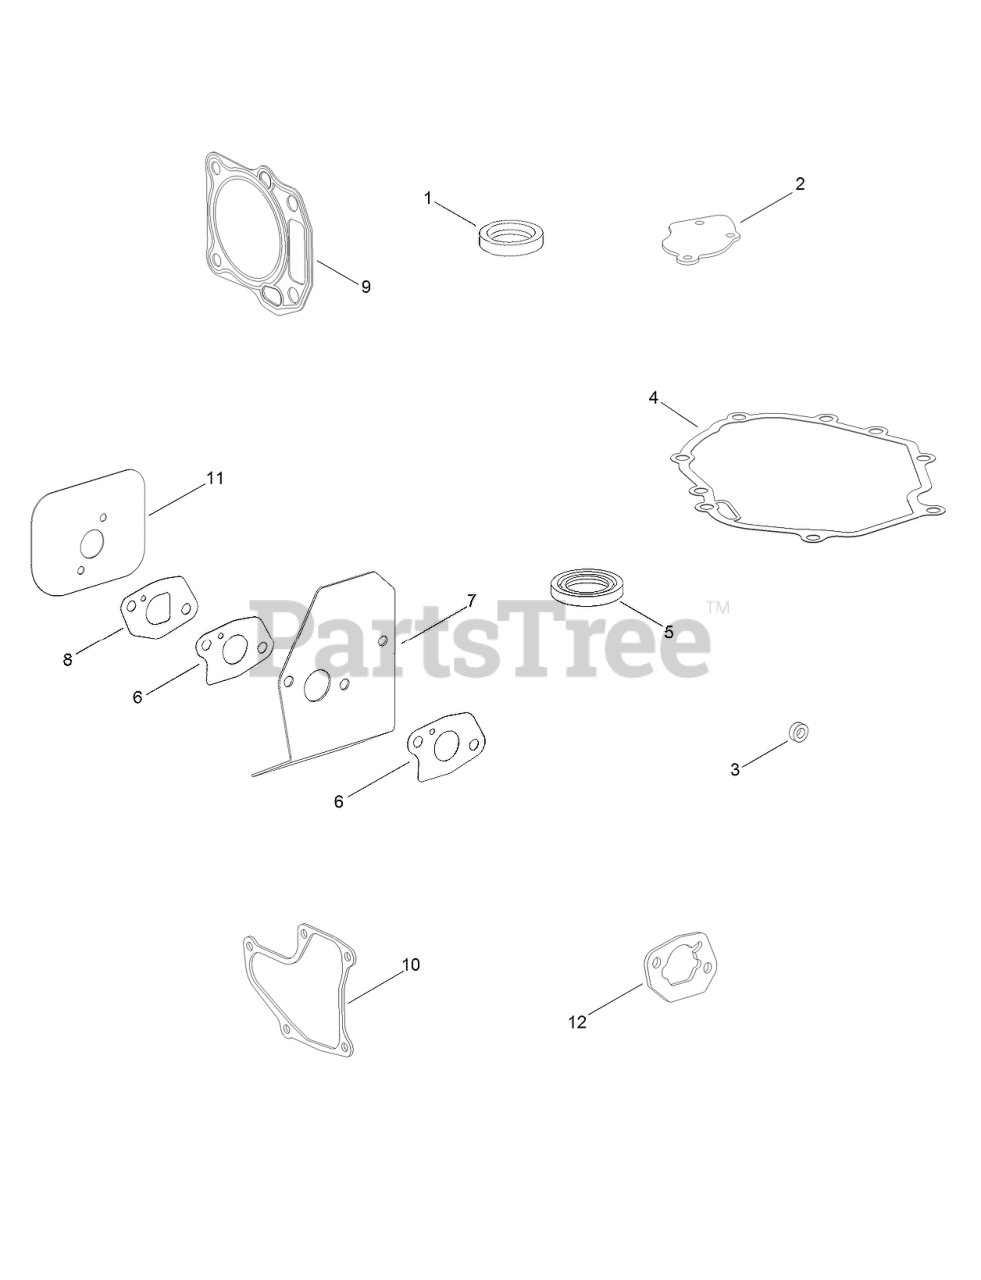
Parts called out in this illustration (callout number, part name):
1	SEAL-OIL
2	GASKET-BREATHER
3	SEAL-OIL
4	GASKET-COVER, CASE
5	SEAL-OIL
6	GASKET-CARBURETOR
7	INSULATOR-CARBURETOR
8	GASKET-INTAKE
9	GASKET-HEAD
10	GASKET-VALVE COVER
11	GASKET-EXHAUST
12	GASKET-AIR CLEANER
